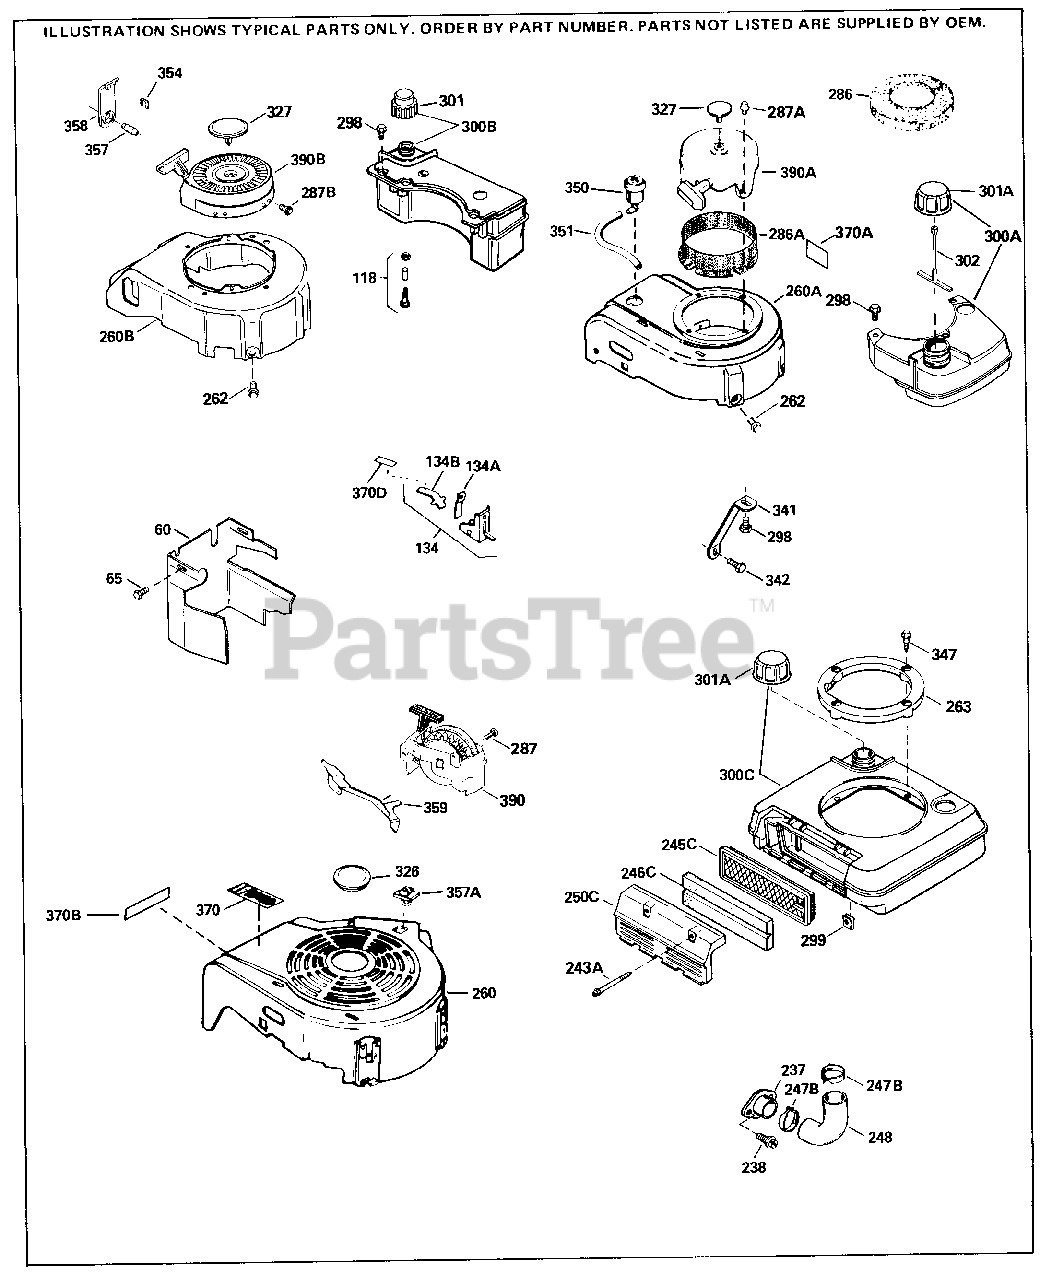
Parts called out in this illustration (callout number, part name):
118	Rope Guide Kit Use as required with 3 4476 fuel tank
134	Spark Plug Stop Lever Incl. 134A & 1 34B
134A	Spring, Stop switch
134B	Clip, Stop switch
238	Screw, 10-32 x 5/8"
246C	Air Filter (also available in Package d Part #740013B)
260A	Housing, Blower
262	Screw, 1/4-20 x 15/32"
286	Starter Screen
287A	Pop Rivet, (3/16" Dia.) Purchase loca lly
287A	Screw, 10-24 x 3/8" (Use as required)
301	Fuel Cap (Red 1-1/2" ID) also availab le in Packaged Part #740005B
370D	Decal, Stop control
390A	Rewind Starter Refer to Division 5, S ection C, page 25 or Fiche 8, Grid G- 7 for breakdown
